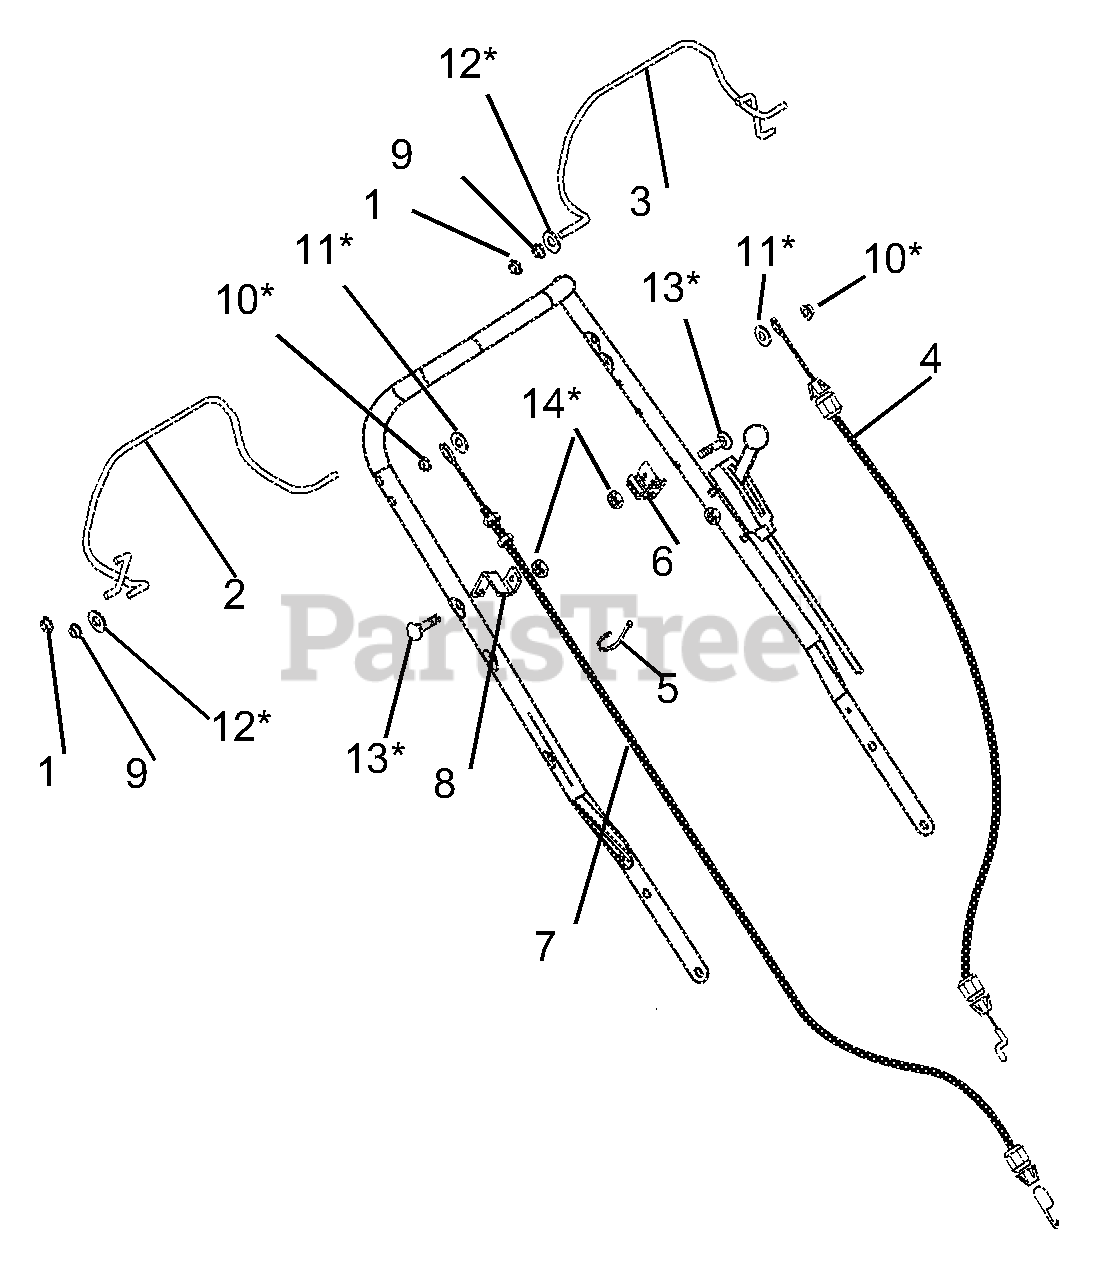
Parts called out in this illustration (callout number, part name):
1	5/16" Push Nut
2	Traction Bail
3	Engine Bail
4	Engine Cable - 51110100
4	Engine Cable - 51110200
4	Engine Cable - 51110300
5	Cable Tie
6	Engine Cable Anchor
7	Traction Cable
8	Traction Cable Anchor
9	5/16" Bushing
10	1/4" Push Nut
11	9/32" Washer
12	1/4" Washer
13	1/2" x 1/4" Bolt
14	1/2" Locknut
